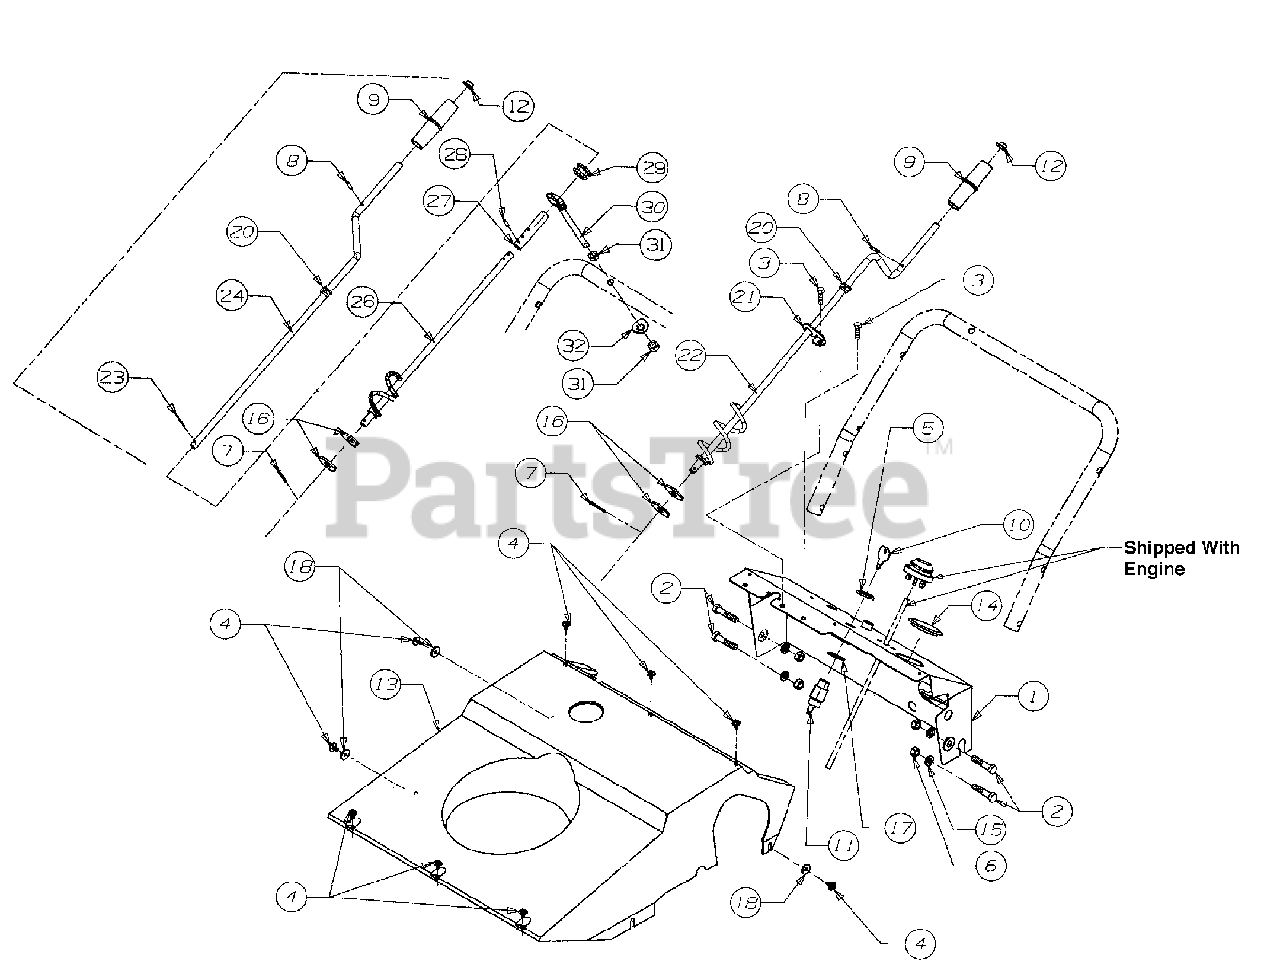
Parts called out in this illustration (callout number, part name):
3	Hex Tap Screw
4	Hex Tap Screw
5	Hex Nut
6	Hex Nut
7	Cotter Pin
9	Chute Crank Knob
10	Key-Ignition
11	Switch-Key
12	Nut Push
13	Shroud
14	Plug
15	Lock Washer
16	Flat Washer
17	Internal Lock Washer
18	Flat Washer
20	Bushing
21	Bracket, Chute Crank
22	Crank Assembly, Chute
23	Cotter Pin
29	Grommet - Rubber
30	Eyebolt - Chute Crank
31	Nut - Hex
32	Washer - Saddle
